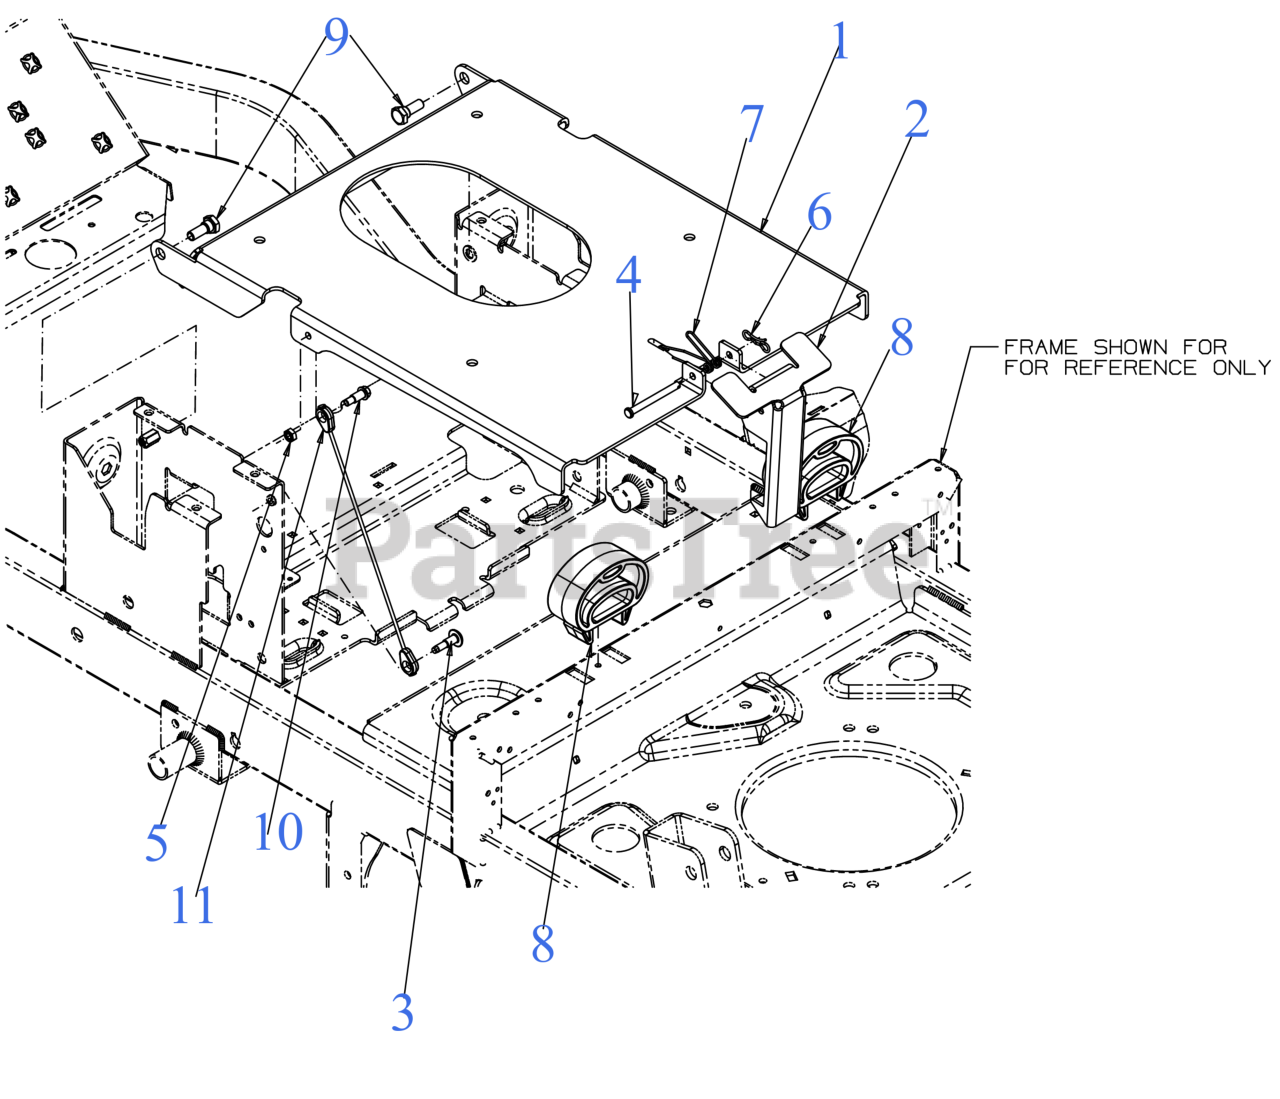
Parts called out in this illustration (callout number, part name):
1	SEAT BASEPLATE
2	SEAT LATCH BRACKET
3	BOLT 1/4-20
4	CLEVIS PIN .248 x 2.345
5	HEX NUT 1/4-20
6	BOW TIE COTTER PIN 1/4-5/16
8	POLYMER SEAT SPRING
9	SHOULDER SCREW .437
10	SHOULDER SCREW
11	SEAT BASE CABLE 10"
